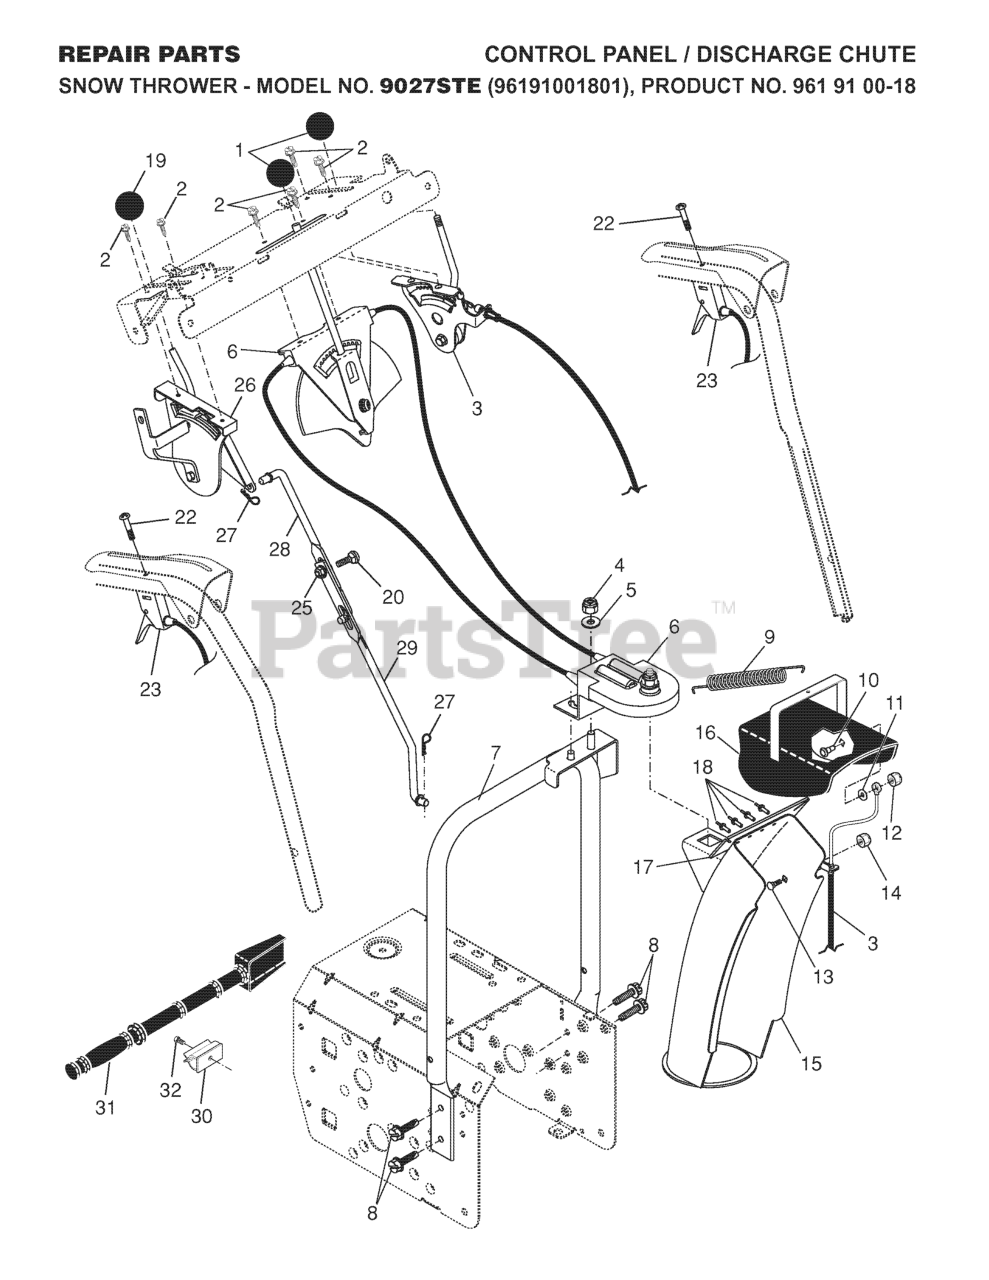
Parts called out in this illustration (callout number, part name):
1	KNOB LEVER, BLACK
2	SCREW #10-24 X 5/8
3	CONTROL.CABLE.DEFLECTOR
4	NUT
5	WASHER
6	CONTROL ASSEMBLY,CHUTE ROTATER
7	SUPPORT, PIVOT
8	SELF-TAPPING SCREW 5/16-18X3/4
9	SPRING.DEFLECTOR.REM.CHUTE
10	BOLT, SHOULDER
11	WASHER, NYLON FRICTION
12	NUT.HEX.FLANGE.1/4
13	BOLT
14	NUT.LOCK.5/16-18
15	CHUTE ASSEMBLY
16	DEFLECTOR.WELDMENT.PNT.ORANGE
17	SEAL, DEFLECTOR
18	RIVET BLIND
19	RED KNOB SHIFTER
20	BOLT
23	STEERING.CONTROL.SNOW.BLUE
25	NUT.FLANGE.5/16
26	HEAD ASSY SPEED
27	SPRING RETAINER
28	ROD, UPPER SPEED CONTROL
29	ROD, LOWER SPEED CONTROL.SNOW
30	CLIP.CLEANOUT.TOOL
31	CLEAN OUT TOOL
32	SCREW.HWH.13-16-5.8.BZP
